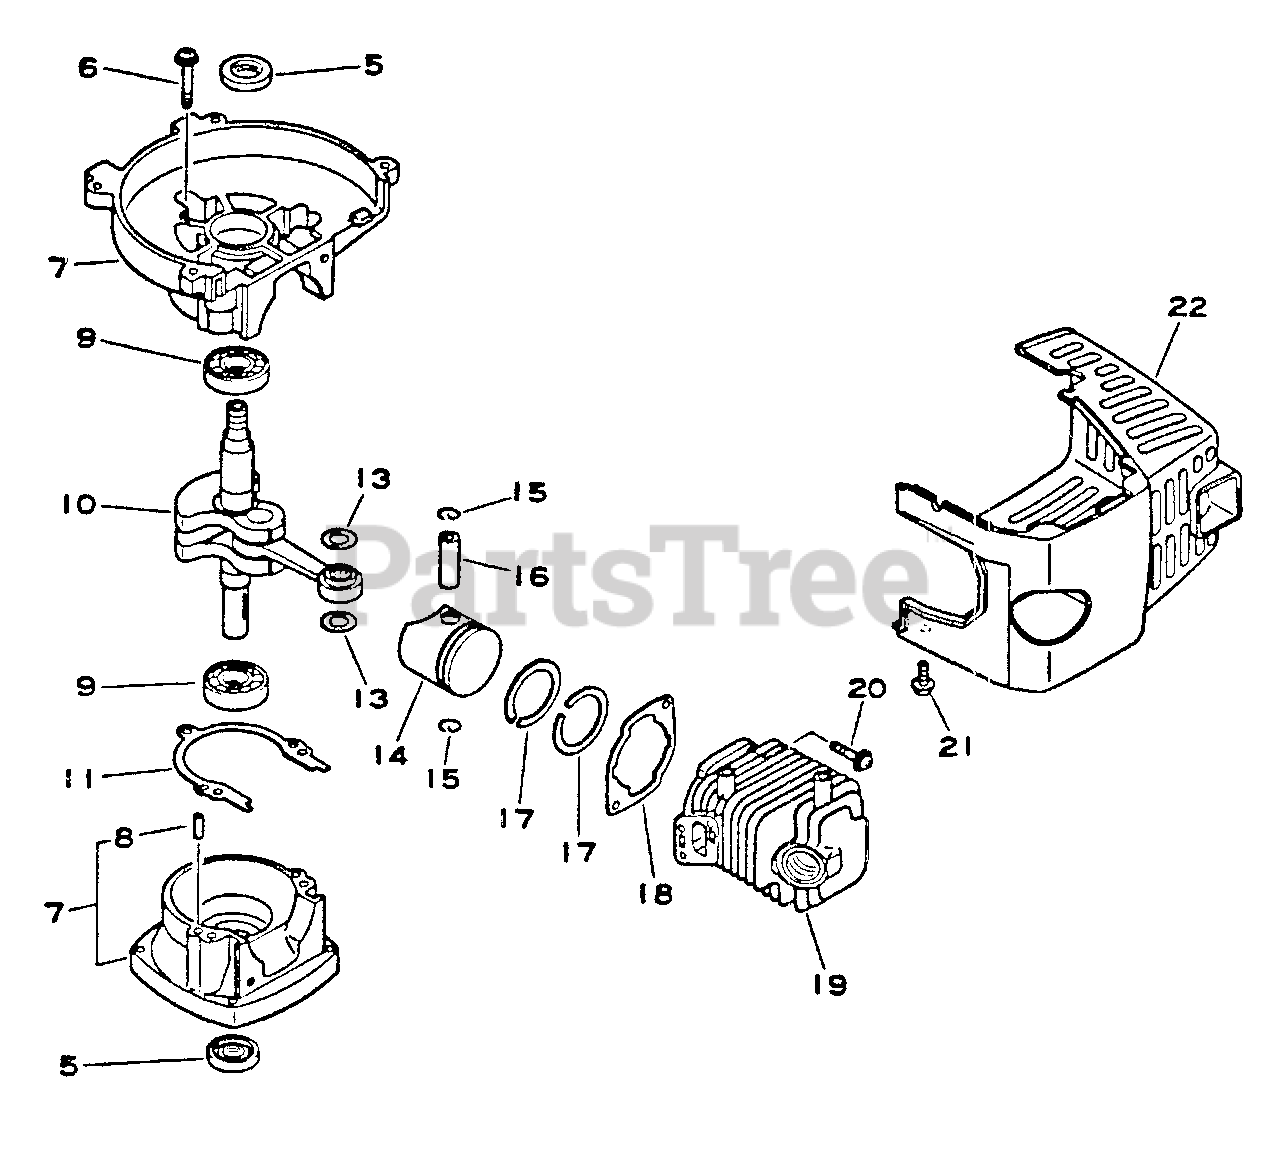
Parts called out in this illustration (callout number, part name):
5	SEAL, OIL 12
6	SCREW 5×28
7	CRANKCASE KIT
8	PIN, LOCATING 4
9	BEARING, BALL - 6201 C3
10	CRANKSHAFT ASSY
11	GASKET, CRANKCASE
13	WASHER, THRUST
14	PISTON
15	RING, SNAP
16	PIN, PISTON 8
17	RING, PISTON
18	GASKET, CYLINDER
19	CYLINDER
20	SCREW 5×22
21	SCREW 4×18
22	COVER, ENGINE
